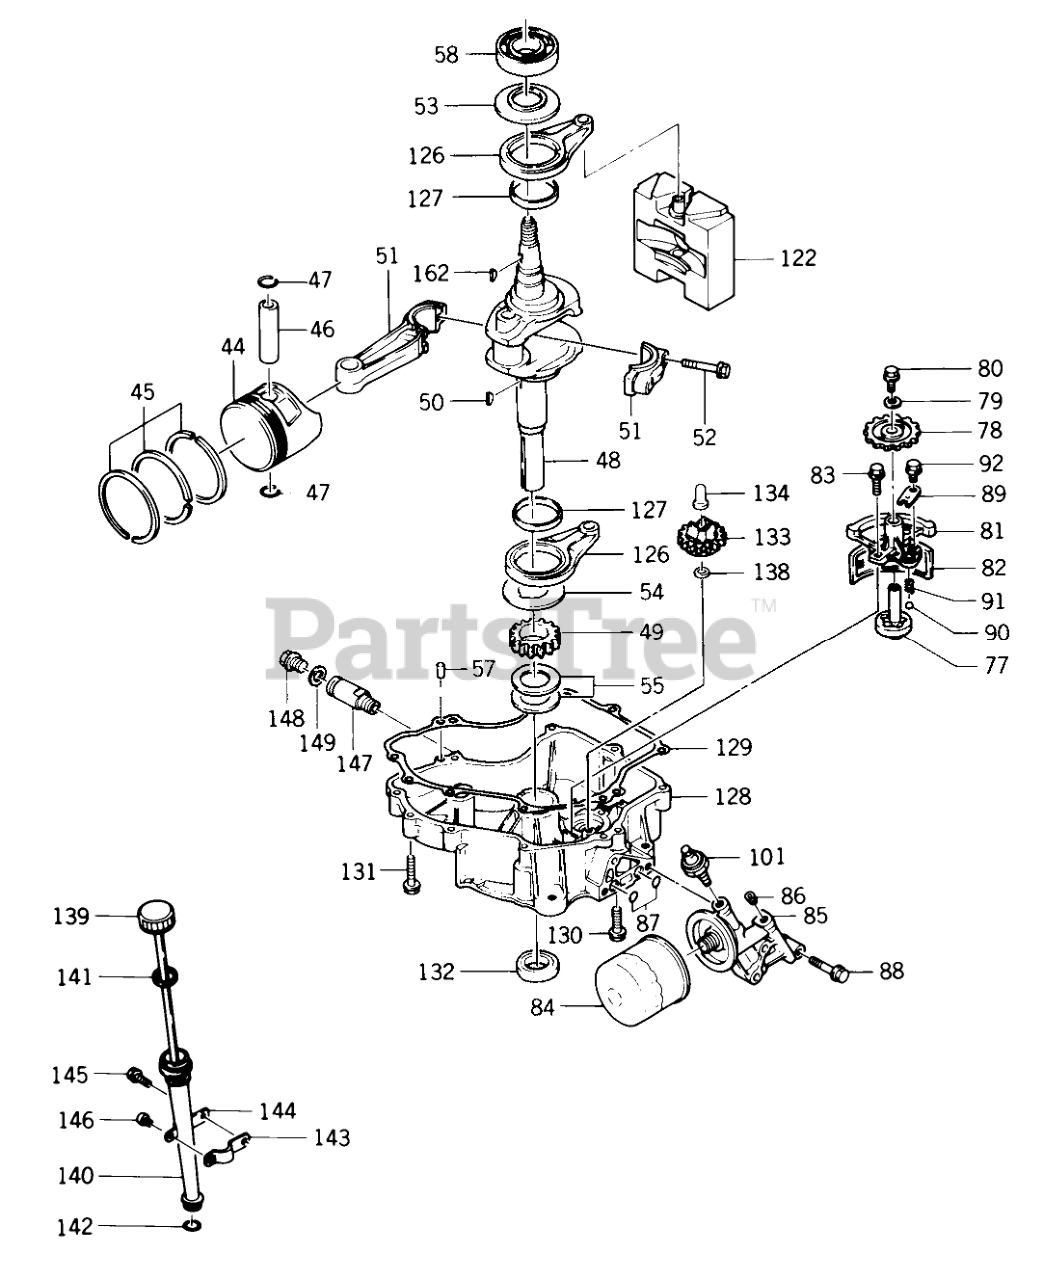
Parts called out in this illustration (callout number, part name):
44	PISTON STD
44	PISTON 0.S.-.25MM
44	PISTON 0.S.-.50MM
44	PISTON 0.S.-.75MM
45	RING PISTON-STD
45	Piston Ring Set-.010 Over Size
45	RING-PISTON-.020
45	RING PISTON-.030
46	PIN PISTON
47	RING-SNAP
48	ASSY-CRANK SHAFT
49	GEAR-HELICAL
50	KEY-WOODRUFF
51	13251-6010 Connecting Rod Assty-Standard Size (Includes item 52)
51	13251-6014 Connecting Rod Assty-0.50mm Under Size (Includes item 52)
52	BOLT-CON ROD
53	SPACER
54	SPACER
55	SHIM-1.18
55	SHIM-1.215
55	SHIM-1.25
55	SHIM-1.60
55	SHIM-1.32
55	SHIM-1.355
55	SHIM-1.425
55	SHIM-1.46
55	SHIM-1.495
55	SHIM-1.53
55	SHIM-1.565
55	SHIM-1.635
55	SHIM-1.67
55	SHIM-1.705
55	SHIM-1.74
58	BEARING-BALL
77	OIL PUMP ASS'Y
78	GEAR-HELICAL COIL
79	WASHER
80	Bolt
81	PUMP COVER COMP
82	FILTER OIL INTERNAL
83	BOLT (8 X 25)
84	Filter-Oil
85	PIPE COMP
87	O-RING
88	BOLT (8 X 40)
89	PLATE
90	BALL-STEEL 5/16
91	SPRING
92	BOLT-FLANGED
101	SWITCH-OIL PRESSURE
122	WEIGHT COMP
126	ASSY-ROD
127	BEARING
128	COVER-CRANKCASE
129	GASKET
130	BOLT (8 X 30)
131	BOLT (8 X 45)
132	SEAL OIL
133	GOVERNON
134	SLEEVE-GOVERNOR
138	WASHER
139	GAGE-OIL
140	TUBE-FILLER
141	GASKET
142	O-RING
143	CLAMP
144	CLAMP
145	Bolt
146	SCREW (6 X 8)
147	JOINT
148	PLUG DRAIN
149	GASKET
162	KEY-WOODRUFF
